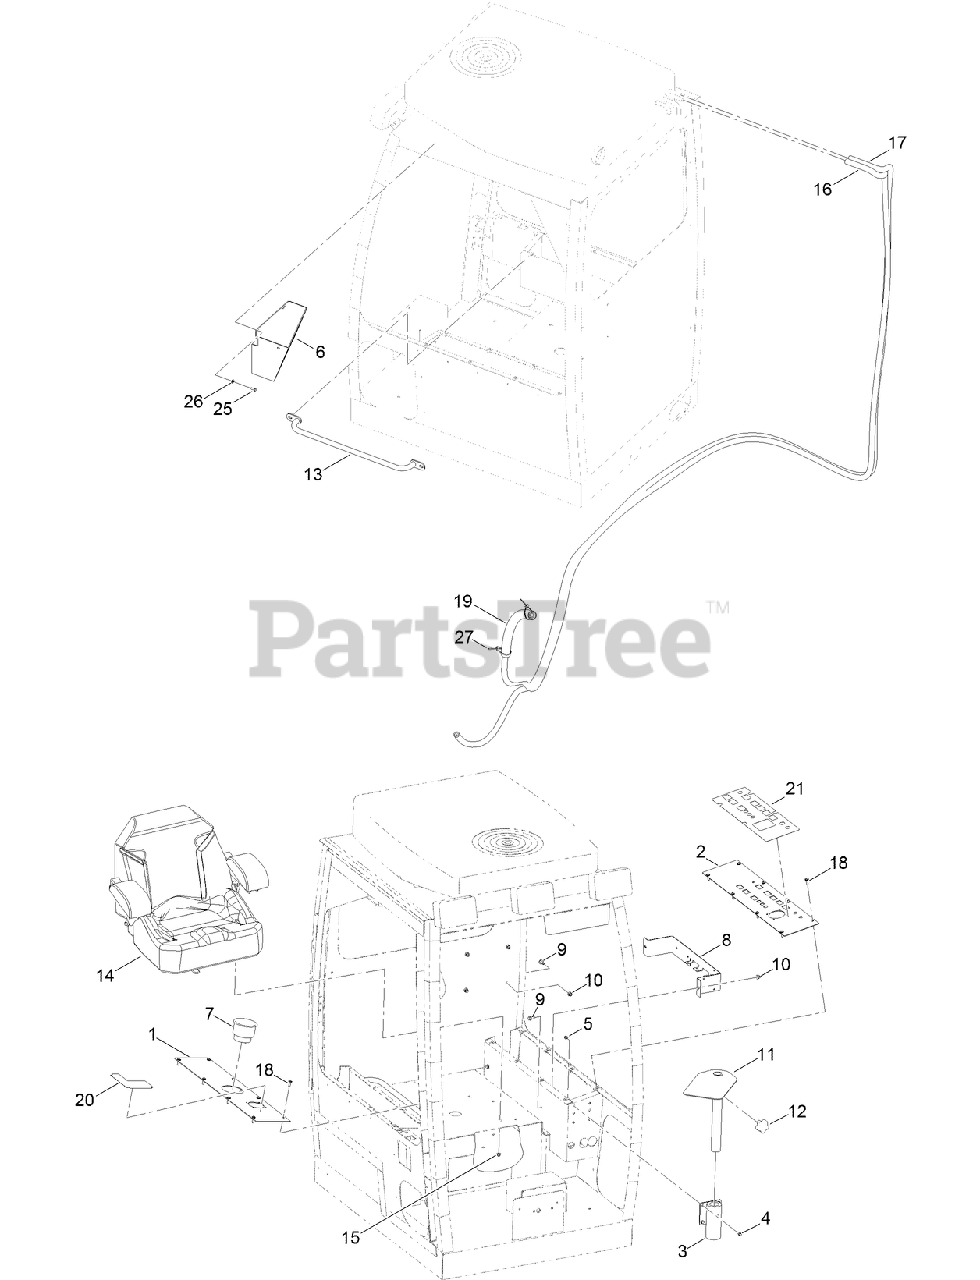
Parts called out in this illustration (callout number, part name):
1	PLATE-CONSOLE, RH
2	PLATE-CONSOLE, LH
3	MOUNT-DISPLAY
4	SCREW-HHF
5	NUT-FLANGE, NI
6	HOUSING-DISPLAY
7	CUP-HOLDER
8	PLATE-MOUNTING, ELECTRICAL
9	SCREW-HHF
10	NUT-LOCK, HHF
11	MOUNT-LOCATOR
12	KNOB-ADJUSTMENT
13	HANDLE-CAB
14	SEAT-TORO, STANDARD
15	NUT-HF, NI
16	HOSE-HEATER
17	HOSE-HEATER
18	SCREW-PPH
19	SLEEVE-THERMAL
20	DECAL-JOYSTICK, RIGHT
21	DECAL-JOYSTICK, LEFT
25	SCREW-HH
26	WASHER-FLAT
27	TIE-CABLE
